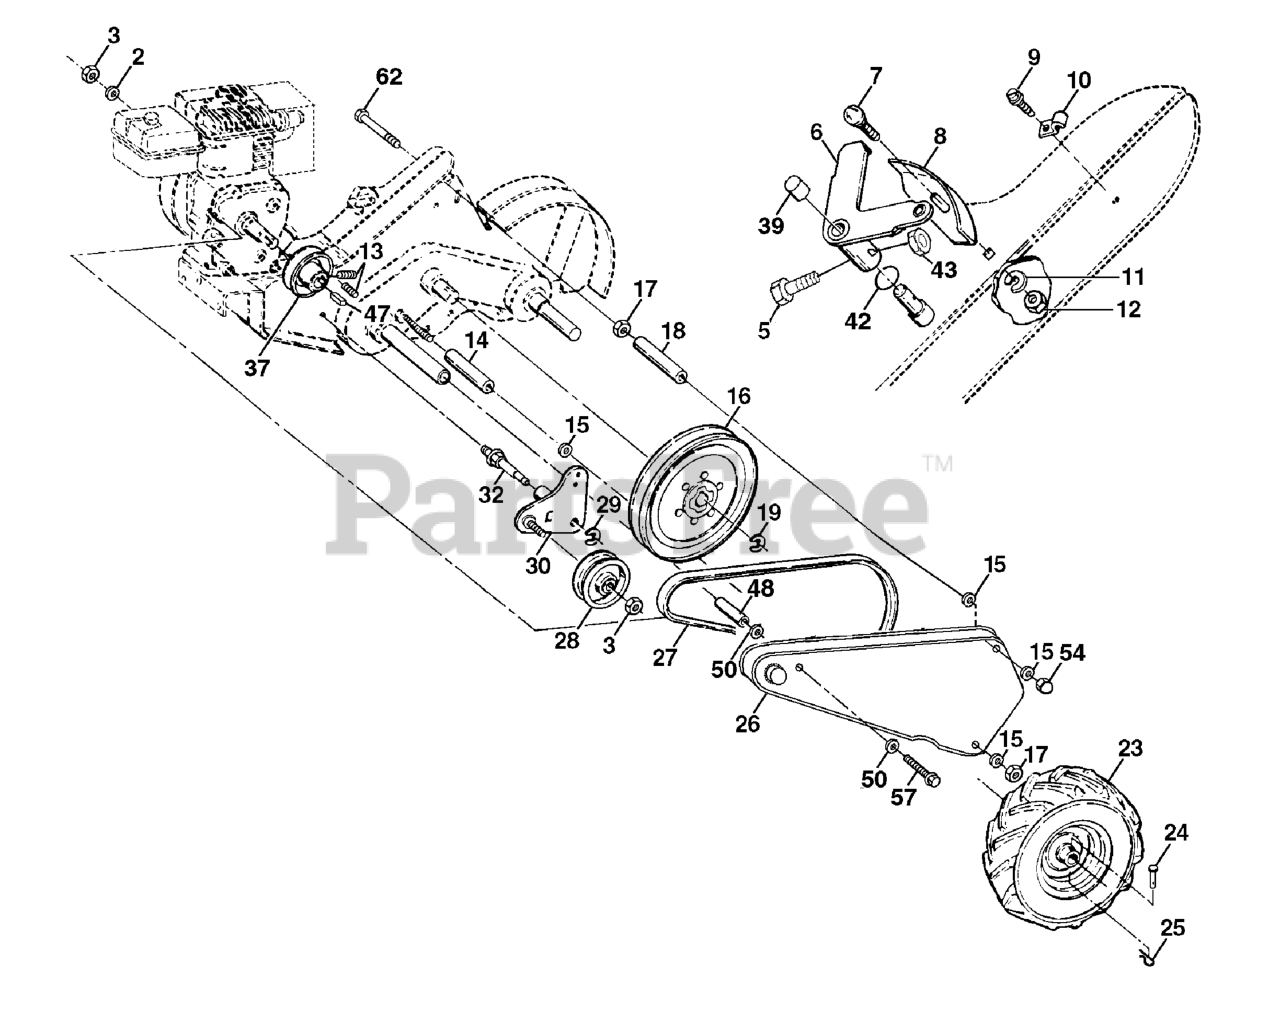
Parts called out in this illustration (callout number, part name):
2	WASHER, LOCK 3/8
3	NUT.HEX.3/8-16UNC
5	SCREW, SHIFT LEVER
6	LEVER ASM CRT
8	PANEL.INDICATOR.SHIFT.BLACK
9	SCREW.HEX.WSH.SLT.#10-24X.50
10	CONDUIT.CLIP.PLATED
11	LOCKWASHER
12	NUT
14	SPACER, SPLIT
15	WASHER
16	SHEAVE, TRANSMISSION
17	NUT
19	RETAINING RING LT
23	TIRE.16X4-8.CHEVRON.TILLER
23	RIM
23	VALVE STEM LT
25	SPRING TI
26	BELT GUARD
27	BELT, DRIVE
28	PULLEY-IDLER TI
30	BRACKET.ASM.IDLER.BLACK
32	SHAFT, IDLER ARM
37	SHEAVE, ENGINE
39	CAP.PLUNGER.BLACK
47	KEY, SQUARE
50	WASHER
57	Bolt, Hex Head 1/2-20 x 2-3/4
62	BOLT 5/16-18X4 1/2
